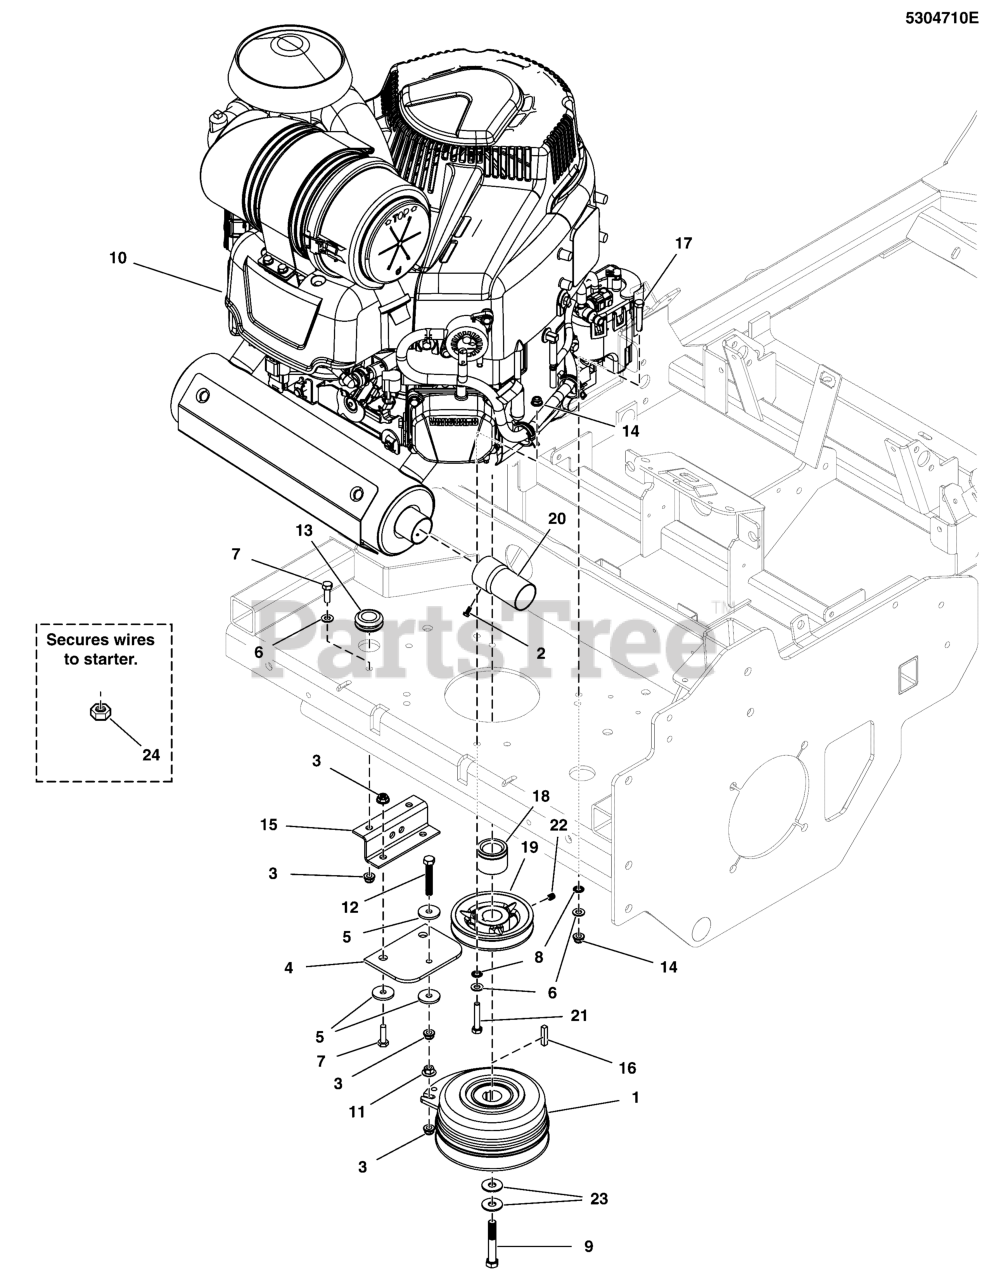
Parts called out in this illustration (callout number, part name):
1	CLUTCH, WARNER, 200 ft lbs - 1.13"
2	SCREW,SELF-TAP,#8-32 X 3/8,WASH HEX, CZ
3	NUT, 5/16-18 HEX NYLOCK FLANGE
4	CLUTCH ANCHOR PAD
5	WASHER, .34 X 1.25 X 10 GA
6	WASHER, 5/16" SAE
7	BOLT, 5/16-18 X 1 GD5 CZ
8	WASHER, 5/16 INT. TOOTH LOCK
9	BOLT, CRANKSHAFT,7/16-20X2-3/4, GD8
11	NUT, 5/16-18 HEX SERRATED FLANGE (LARGE)
12	BOLT, 5/16-18 X 2-1/4 TFL, GD5 YZ
13	GROMMET, 7/8"ID, 1/4" THICK STK
14	NUT, 5/16-24, TOP LOCK FLANGE, GD8 PHOS
15	ANCHOR, CLUTCH - BLK
16	KEY, 1/4 SQ X 1-1/4
17	BOLT, 5/16-24 X 1-1/2, GD8, PHOS
18	SPACER, 1.13 X 1.75 X 1.35, CZ
19	PULLEY, 4.75 OD X 1-1/8 BORE, BC-48
20	EXTENSION, TAILPIPE, 3", BLACK
21	BOLT, 5/16-24 X 1-3/4, GD8, PHOS
22	SET SCREW, 5/16-18 X 3/8, KNURL W/ PATCH
23	BELLEVILLE WASHER 1.1875 X .442 X .089
24	NUT, 5/16-24 JAM
